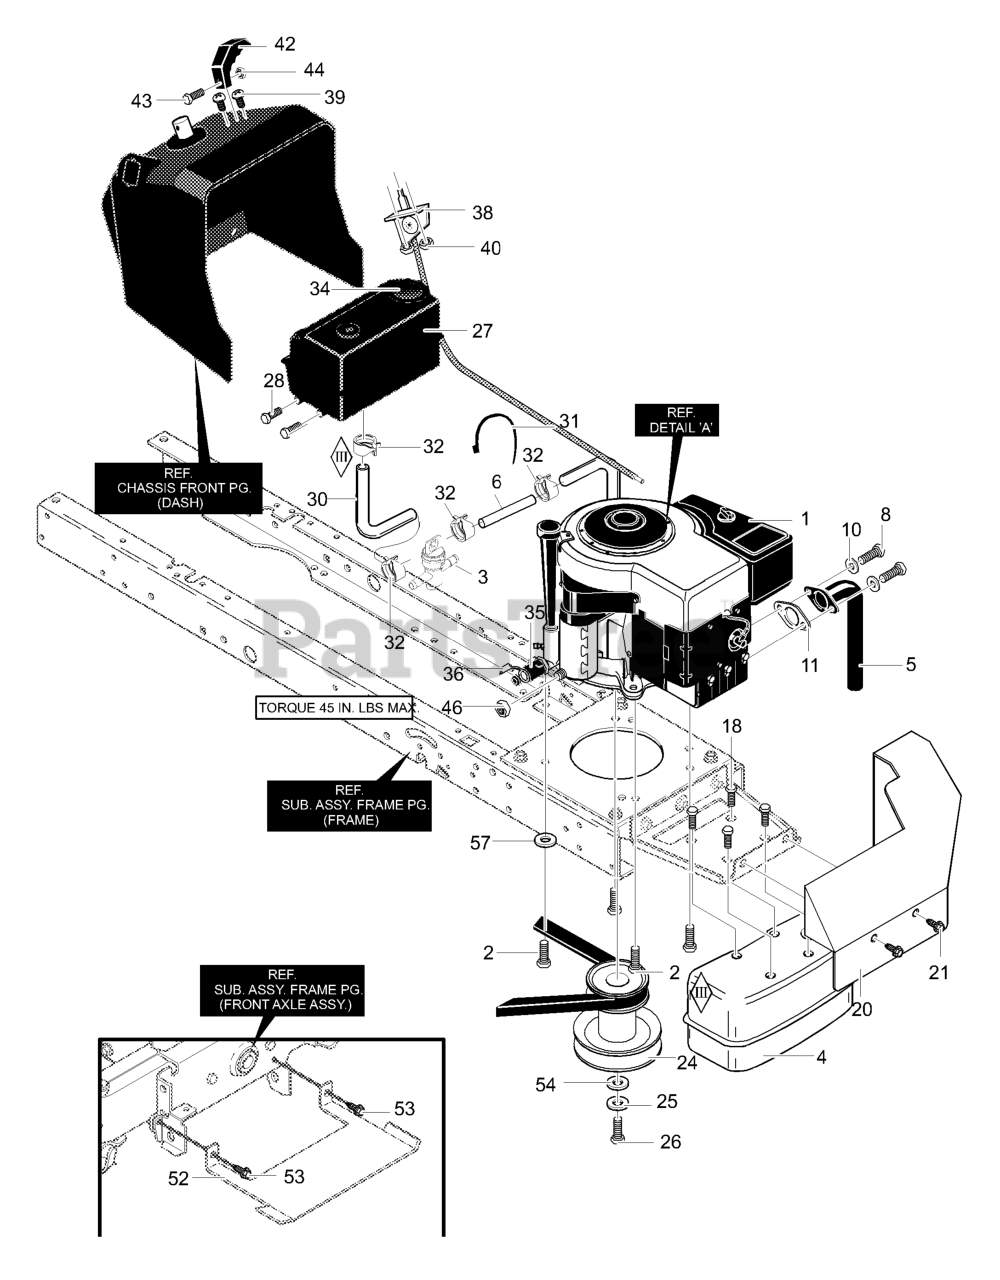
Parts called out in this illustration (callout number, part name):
1	12.5HP Engine
2	Engine Bolt
3	Fuel Shut Off Valve
4	Muffler, Super Low
5	Exhaust Pipe
6	Gas Line Tubing 3 Inches
8	Screw, 5/16-18 x 0.75
10	Washer, Hvsptlk
11	GASKET, Exhaust
18	Screw, 1/4-20x.63
20	Heat Shield Assembly
21	Screw, 5/16-18 x 0.75
24	Stack Pulley
25	Washer, Regsptlk
26	Screw, 7/16-20
27	Tank, Fuel 1.5 Gal.
28	Screw, 15TPIX
30	Gas line 8 Inches
31	Cable Tie
32	Clamp, Fuel Clamp
34	Gas Cap
35	Oil Drain Valve Assembly
36	Cap, Oil Drain Valve
38	Throttle Control
39	Screw, 10-24x.63
40	Nut, #10-24
42	Knob, Throttle Control
43	Screw, #8-32
44	Nut, #8-32
46	Nut, 1/4-20
52	Shield, Anti-Dehydration
53	Screw, 5/16-18 x 0.75
54	Washer, Flat
57	Washer, Exlk
